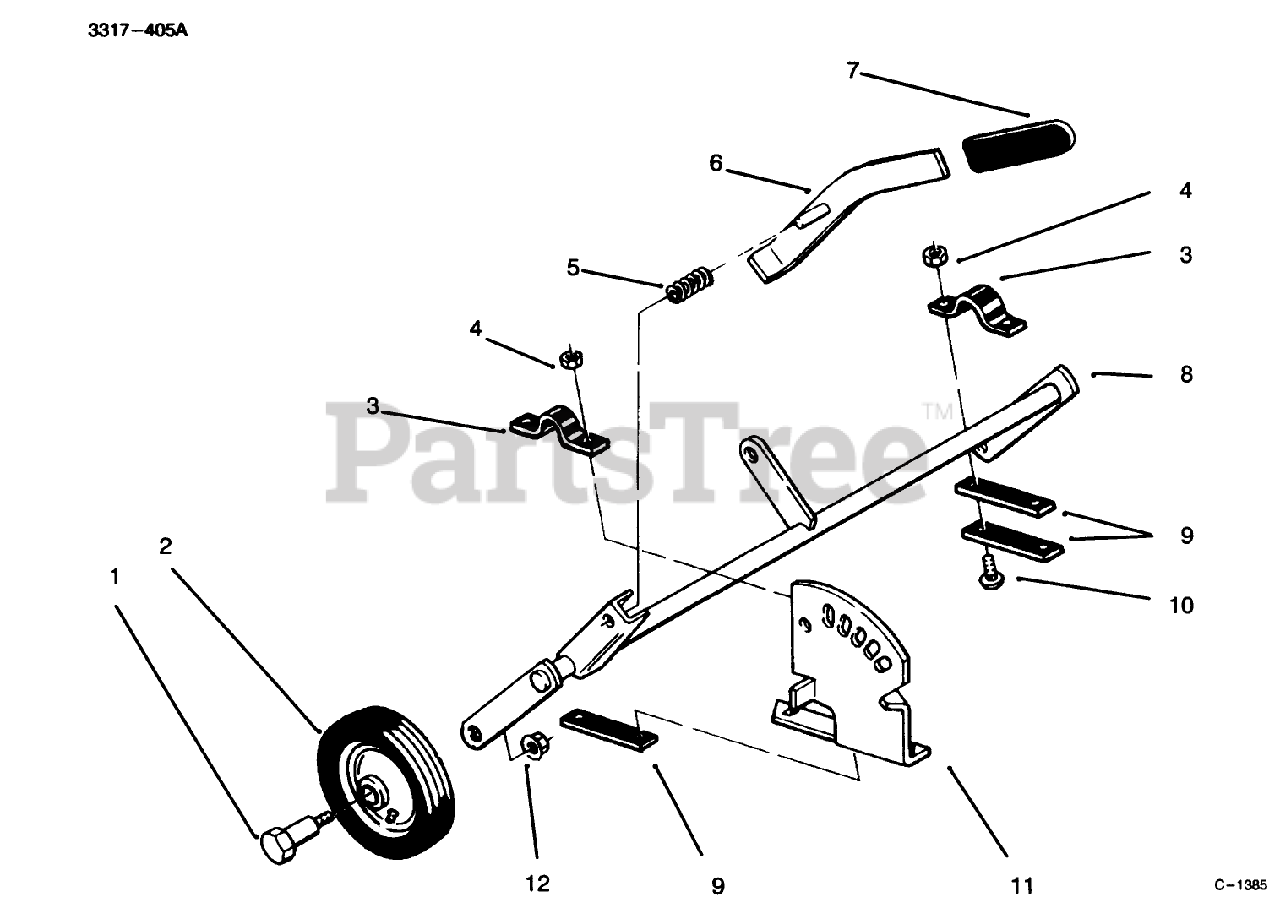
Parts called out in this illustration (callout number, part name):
1	BOLT-SHOULDER
2	WHEEL
3	CLAMP
4	NUT-LOCK, NI
5	SPRING-COMPRESSION
10	BOLT-CARR
